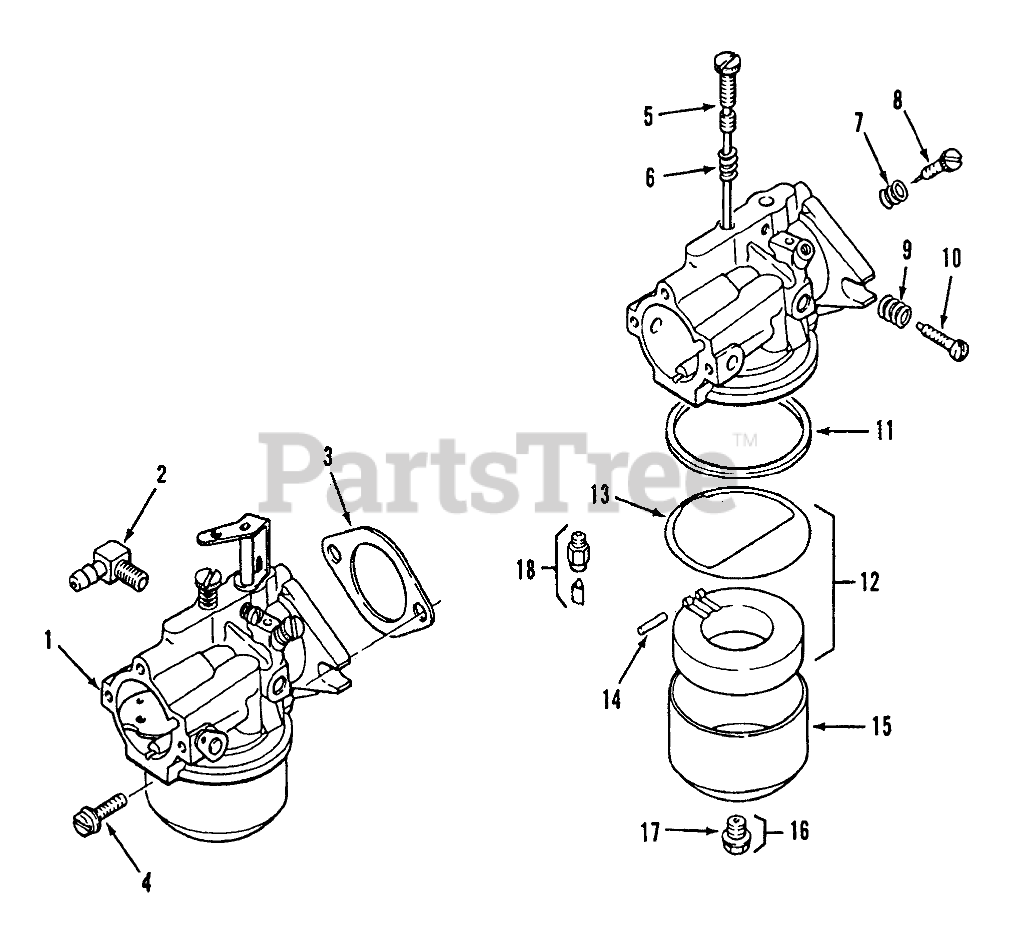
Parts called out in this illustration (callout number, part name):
1	Carburetor Assembly (Includes 5 thru 8), 312
2	90 Degree Hose Connector
3	Gasket-Carburetor
4	Screw sitd. hd.
5	Main Fuel Adj. Needle 312
6	Spring-Main
7	Spring-Idle
8	09GN3665 36 SNWTHWR
9	Spring-Idle Speed
10	Screw
11	Gasket-Bowl
12	Float Kit (Includes Item 13)
13	Gasket-Bowl Baffle
14	Pin-Float Hinge
15	Bowl
16	Fuel Bowl Retainer Screw (Includes Item 17)
17	Gasket-Bowl Screw
18	Needle and Seat-Available Only In Carburetor Repair Kit
